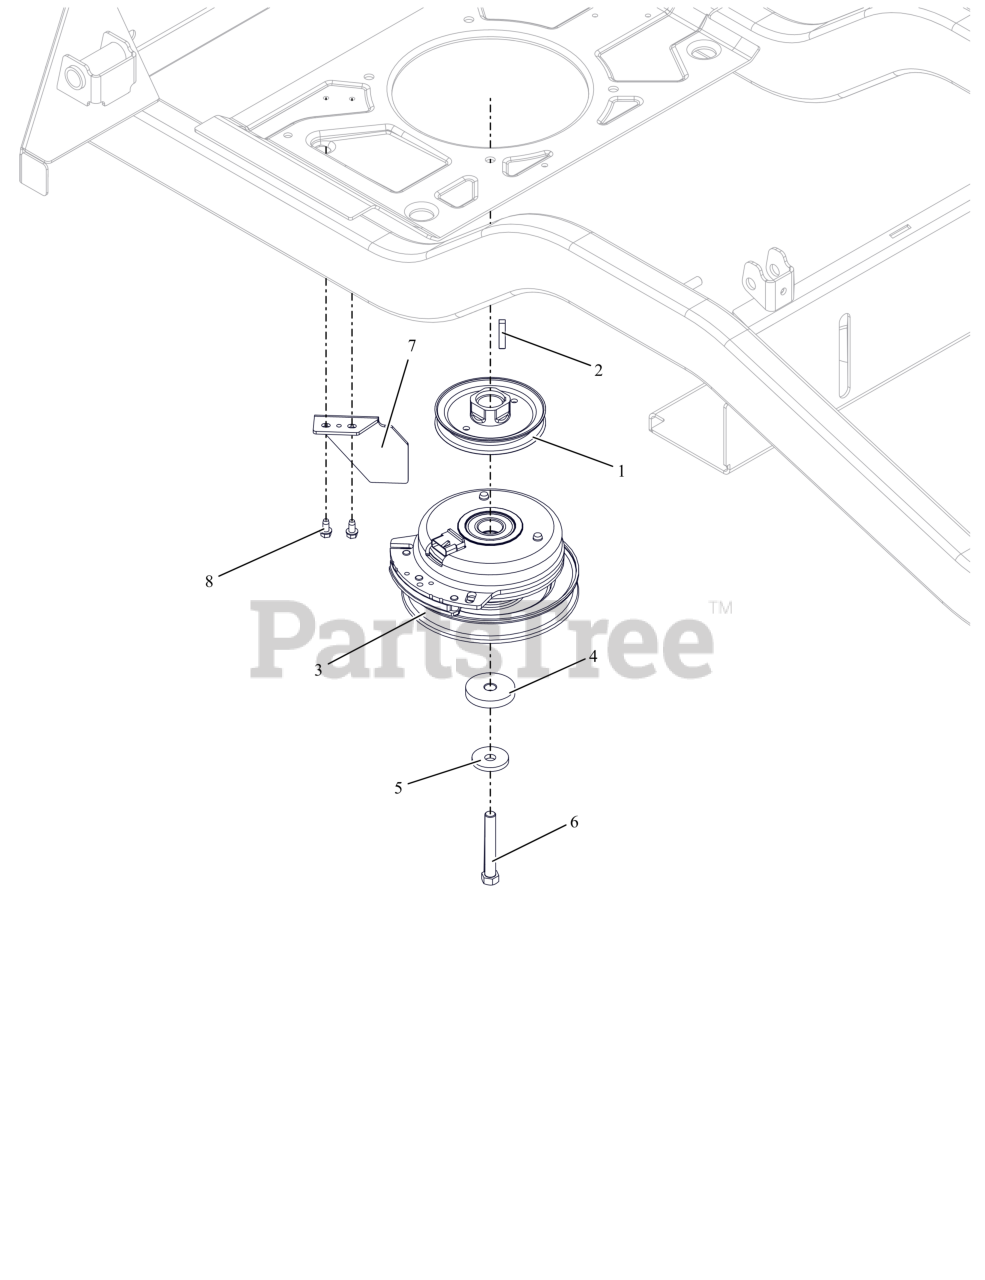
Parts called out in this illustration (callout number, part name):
1	WLDMT-PULLEY-4.50ODX1.003
2	KEY-SQ .25 X 1.25 X .25 SAE
3	CLUTCH- WARNER 1.00 HD-PTZ
4	SPACER, .474/.459X2.00X.350
5	WASHER, 7/16" SPRING DISK
6	BLT, HEX 0.4375-20X3 G8 ZCC NT
7	BRKT- CLUTCH STOP HD
8	SCR-TAP .25-20X.50 HWH ZCC
